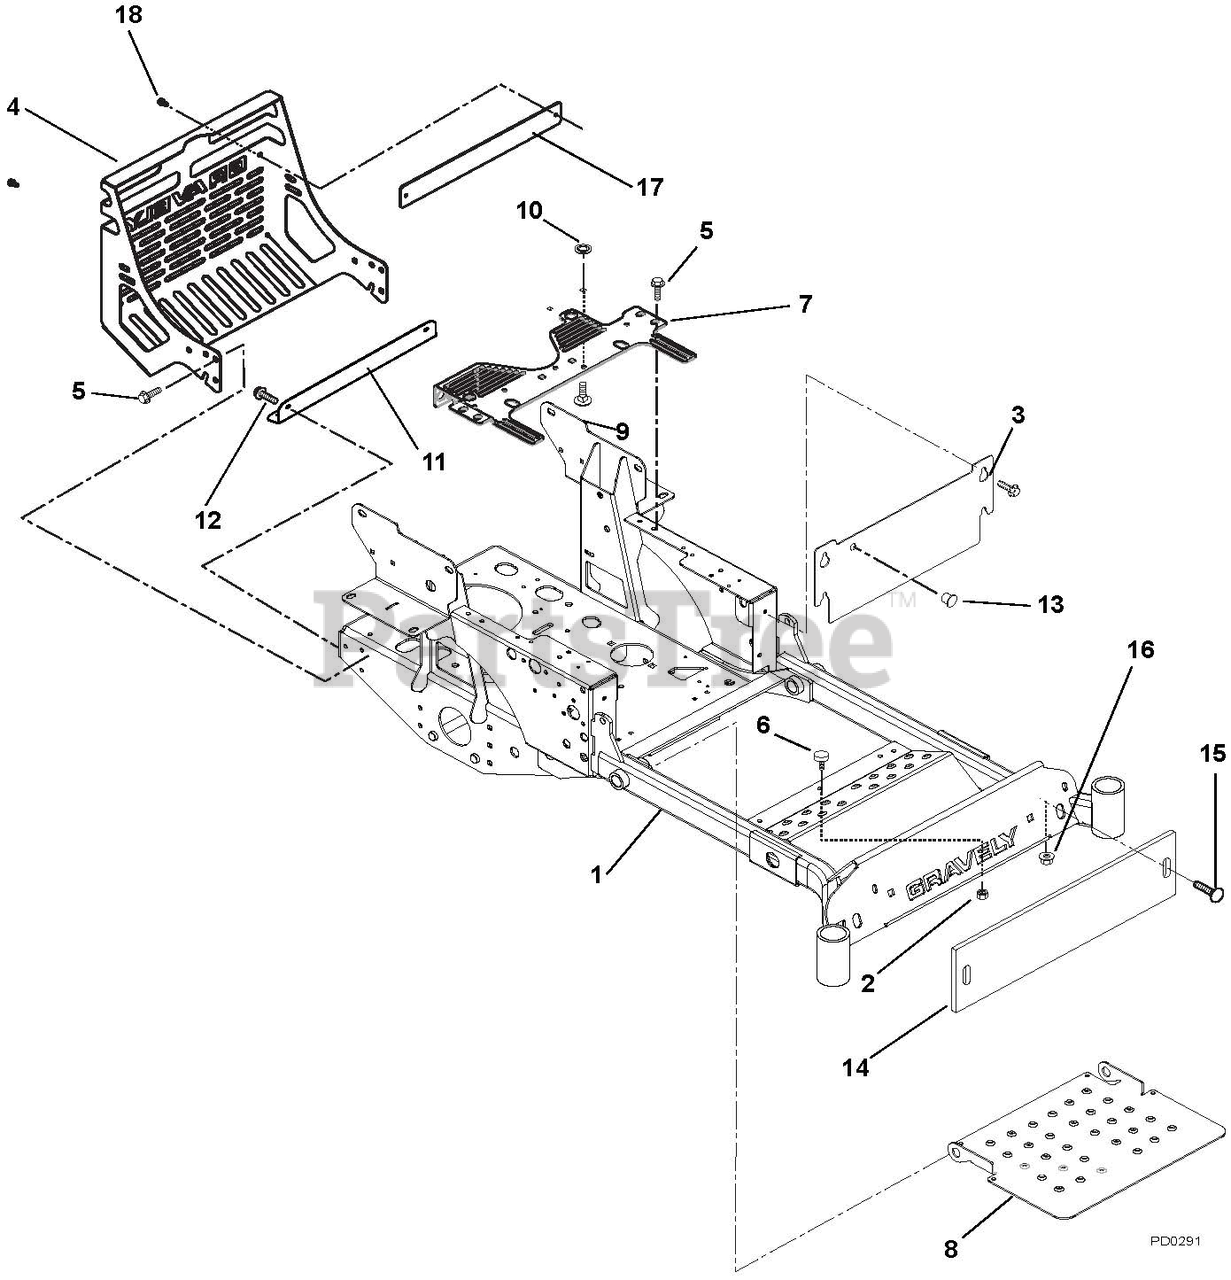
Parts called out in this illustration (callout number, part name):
1	Frame, Compact-Z
2	Nut, Spin Lock Flange .312-18
3	Access Panel
4	Bumper, Rear
5	Screw, Tapping .38-16 x .75 Hex Washer Head
6	Bumper, Rubber
7	Seat Support
8	Panel, Inspection
9	Bolt, Round Head Square Short Neck .31-18 x .75 Grade 5
10	Nut, Push .312
11	Heat Shield
12	Screw, Tapping .38-16 x .50 Hex Washer Head
13	Plug, Hole .56
14	Counterwieght CZ Front – Black
15	Bolt, Round Head Square Neck .50-13 x 2.50 Grade 5
16	Nut .50-13 Nyloc Flange
17	Plate, Bumper
18	Screw, Tapping .25-20 x .50 Hex Washer Head
19	Bracket, Mounting Right Hand
20	Bracket, Mounting Left Hand
21	Screw, Tapping .25-20 x .50 Hex Washer Head
